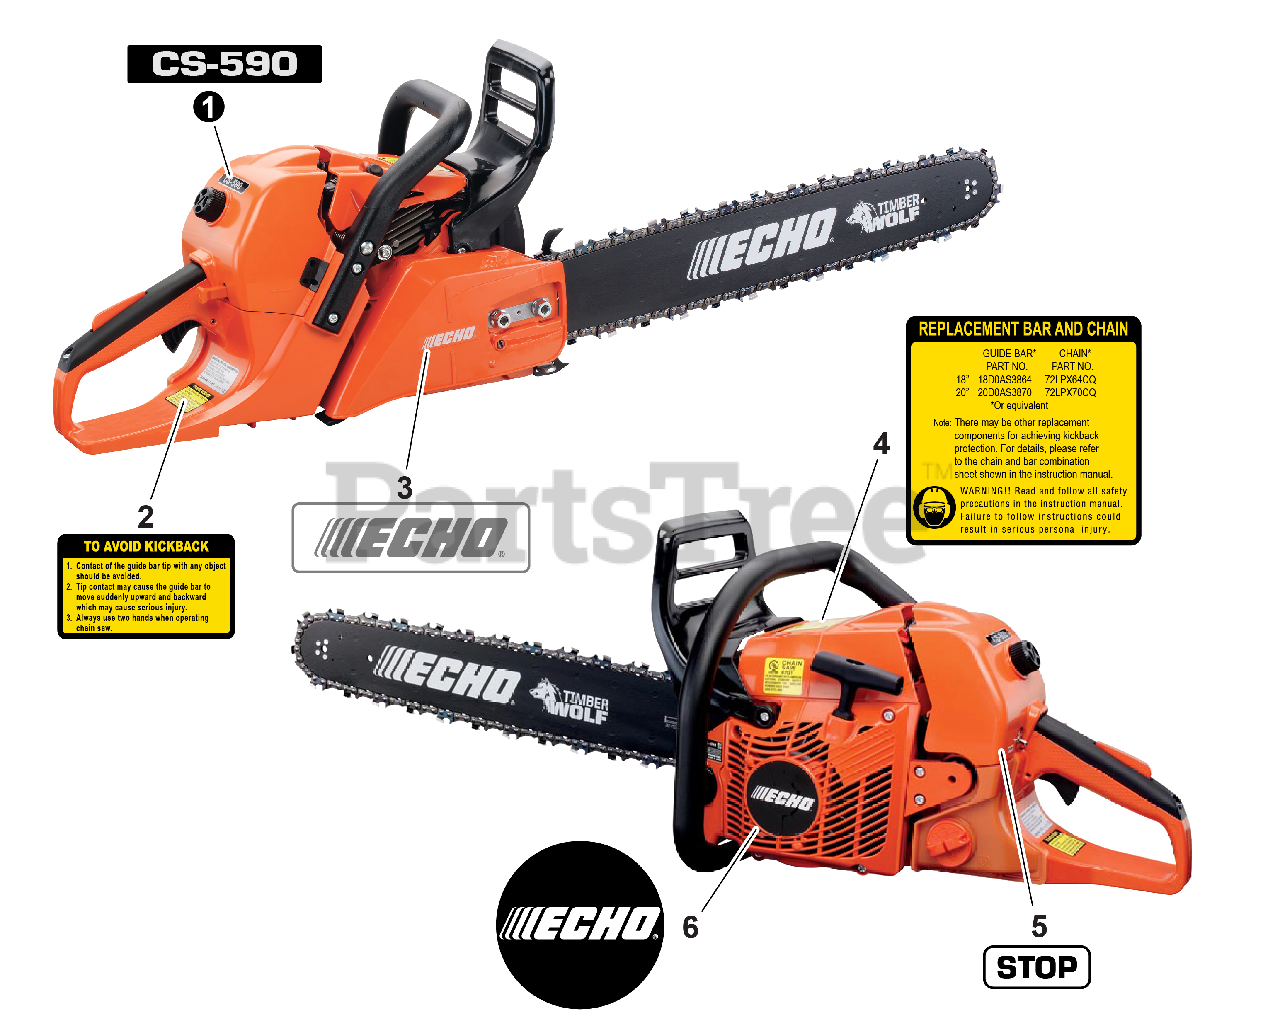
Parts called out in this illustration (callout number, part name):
1	LABEL - MODEL - CS-590
2	LABEL - KICKBACK
3	LABEL - ECHO
4	LABEL - BAR & CHAIN
5	LABEL - STOP
6	LABEL - ECHO
